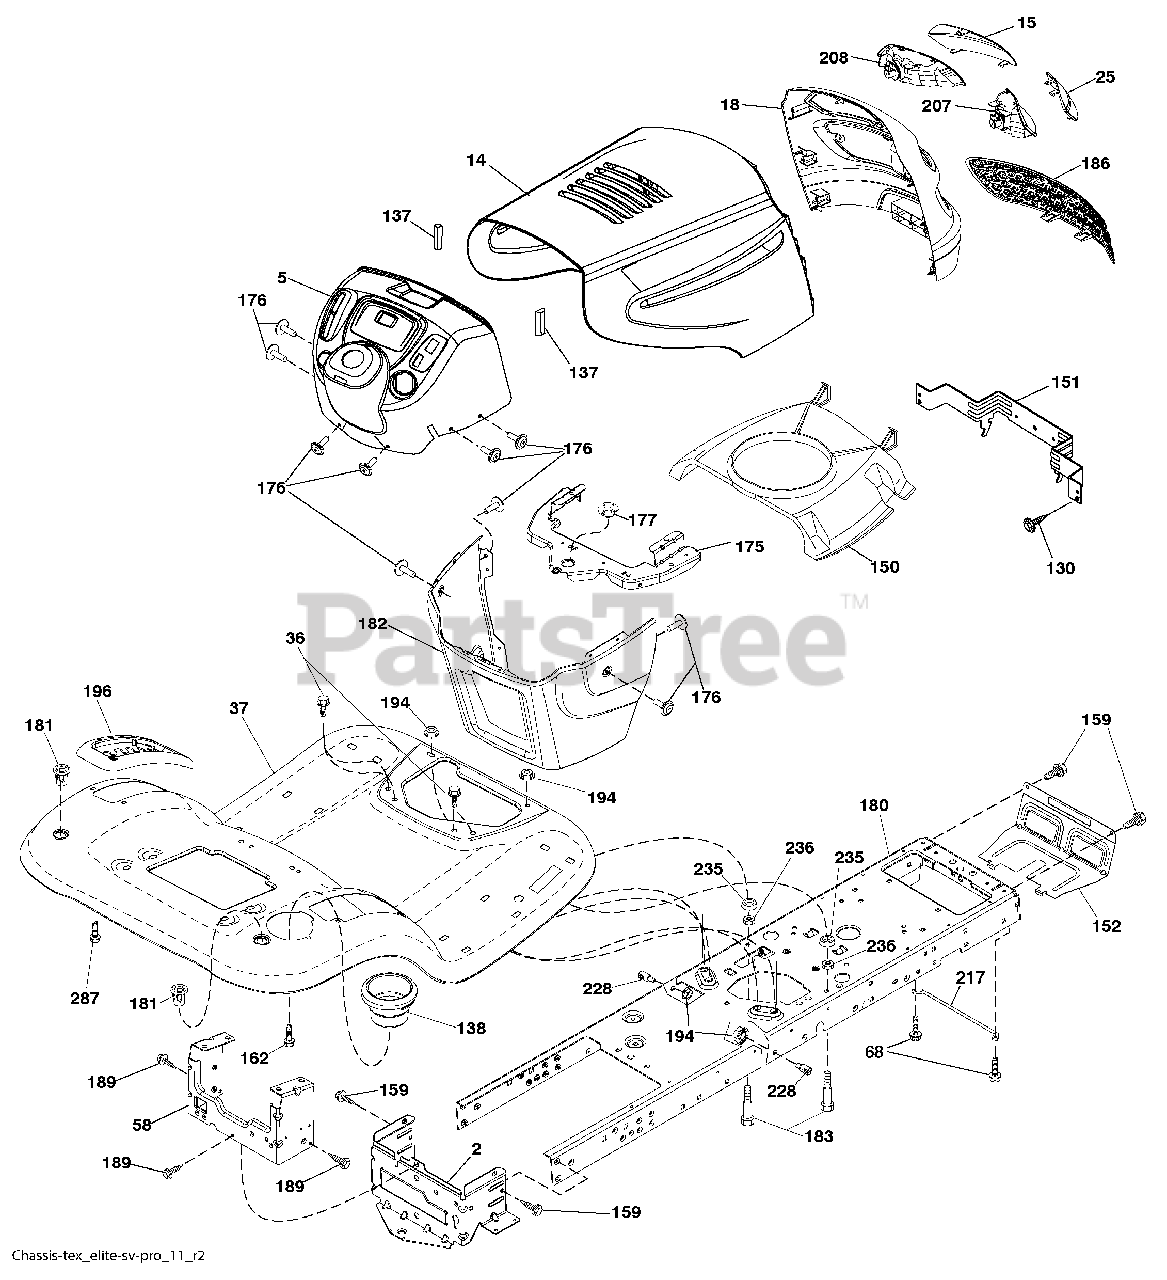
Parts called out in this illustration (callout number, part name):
2	Drawbar
14	Hood
15	Lens Grille LH
18	Grille
25	Lens Grille RH
36	Screw 5/16-18 x 3/4
37	Fender
58	Drawbar, Upper 2 PC SML Fender
68	Screw THDROL 5/16-18 x 1/2
130	Screw #10 x 0.750 BOS Thread
137	Bumper Hood
138	Cupholder
150	Duct Heat Hood
151	Bracket Pivot
152	Shield Browning/Debris
159	Screw Hexwsh Thdrol 3/8-16 x 3/4
162	Screw Hex Wsh Hi-Lo 1/4 x 1/2 unc
175	Crossmember
176	Screw 10-24 x 5/8 Wshd Qdrx
177	Bushing Steering
181	Bushing Mtg. Fender Crgo.
182	Dash Lower
183	Bolt Fin Hex 5/16-18 x 1-1/4
189	Screw 5/16-18 x 3/4
194	Nut Lock Hex Flange 5/16-18
196	Console Asm. Deck Lift
207	Bezel RH
208	Bezel LH
217	Rod Pivot Chassis
228	Stud Fastener
235	Spacer Fender
236	Nut Center Lock 5/16-18 unc
287	Screw Hex Washead 1/4-20 x 3/8
